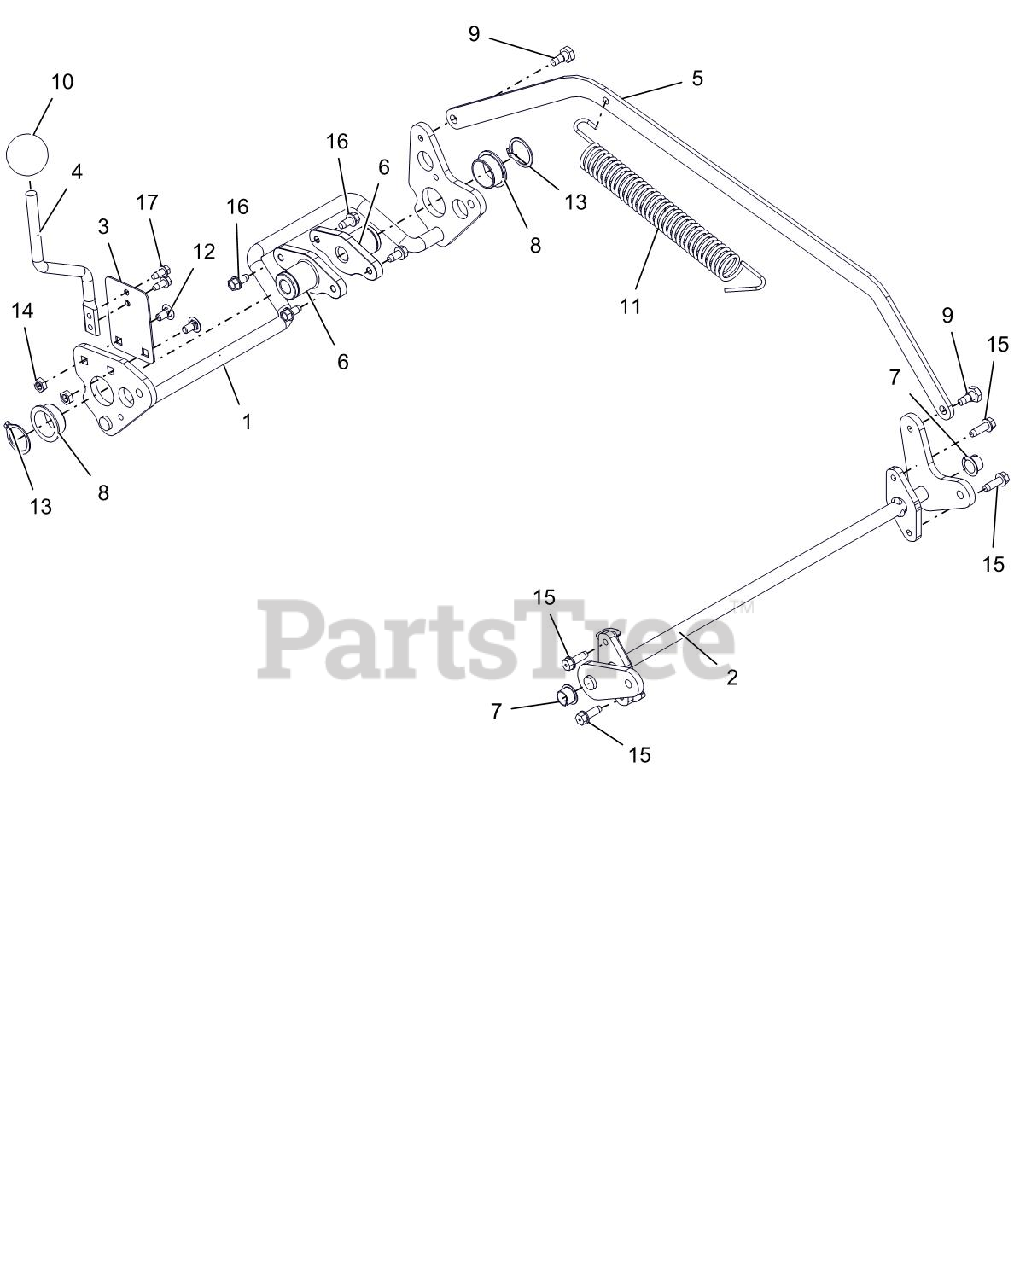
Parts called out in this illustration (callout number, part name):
1	WLDMT, REAR AXLE
2	WMT, LM FRONT AXLE
3	PLATE, HOC SPRING
4	LEVER, HOC ADJUSTMENT
5	LINKAGE, HOC CONNECT
6	HUB, LM REAR AXLE
7	BUSHING, POLYLINER-.50 SPLIT
8	BSHG-FLG 1.0X1.125X.50X1.375 R
9	BOLT, SHLDR .320X.210X.25-20
10	KNOB,BALL -BLACK 1.47" .375-16
11	SG-TENS .121X1.00X6.5 WLD
12	@BLT-RDHDSQNK .25-20X.50 G5YZ
13	RG-RTNG-EXT 1.00X.042
14	NUT-LK-CTR JAM .25-20 YWZC
15	SCR-TAP-PM .25-20X.75 TR YWZ
16	SCR-TAP .25-20X.50 HWH TR YWZ
17	@SCR-TAP 12-24X.50 HWH TR YWZC
